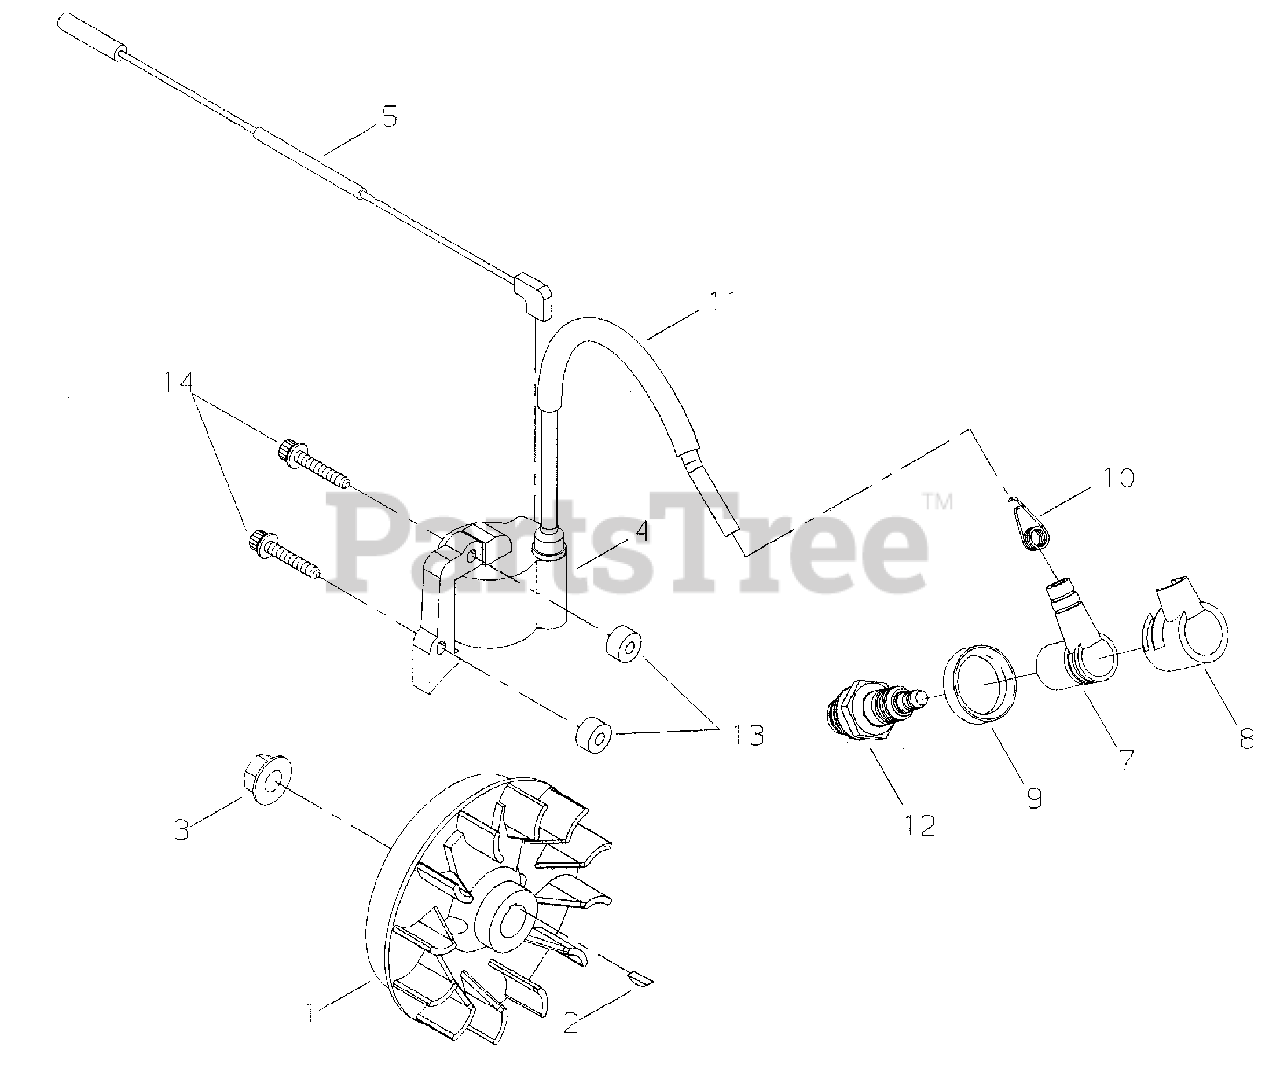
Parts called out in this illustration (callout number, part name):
1	FLYWHEEL
2	KEY - 3X10
3	NUT - 8
4	IGNITION COIL ASSY
5	LEAD - IGNITION
7	CAP, SPARK PLUG
8	CAP, SPARK PLUG
9	SEAL, DUST
10	TERMINAL, SPARK PLUG CAP
11	TUBE
12	SPARK PLUG -- CJ-8Y
13	INSULATOR
14	SCREW - 4X26
